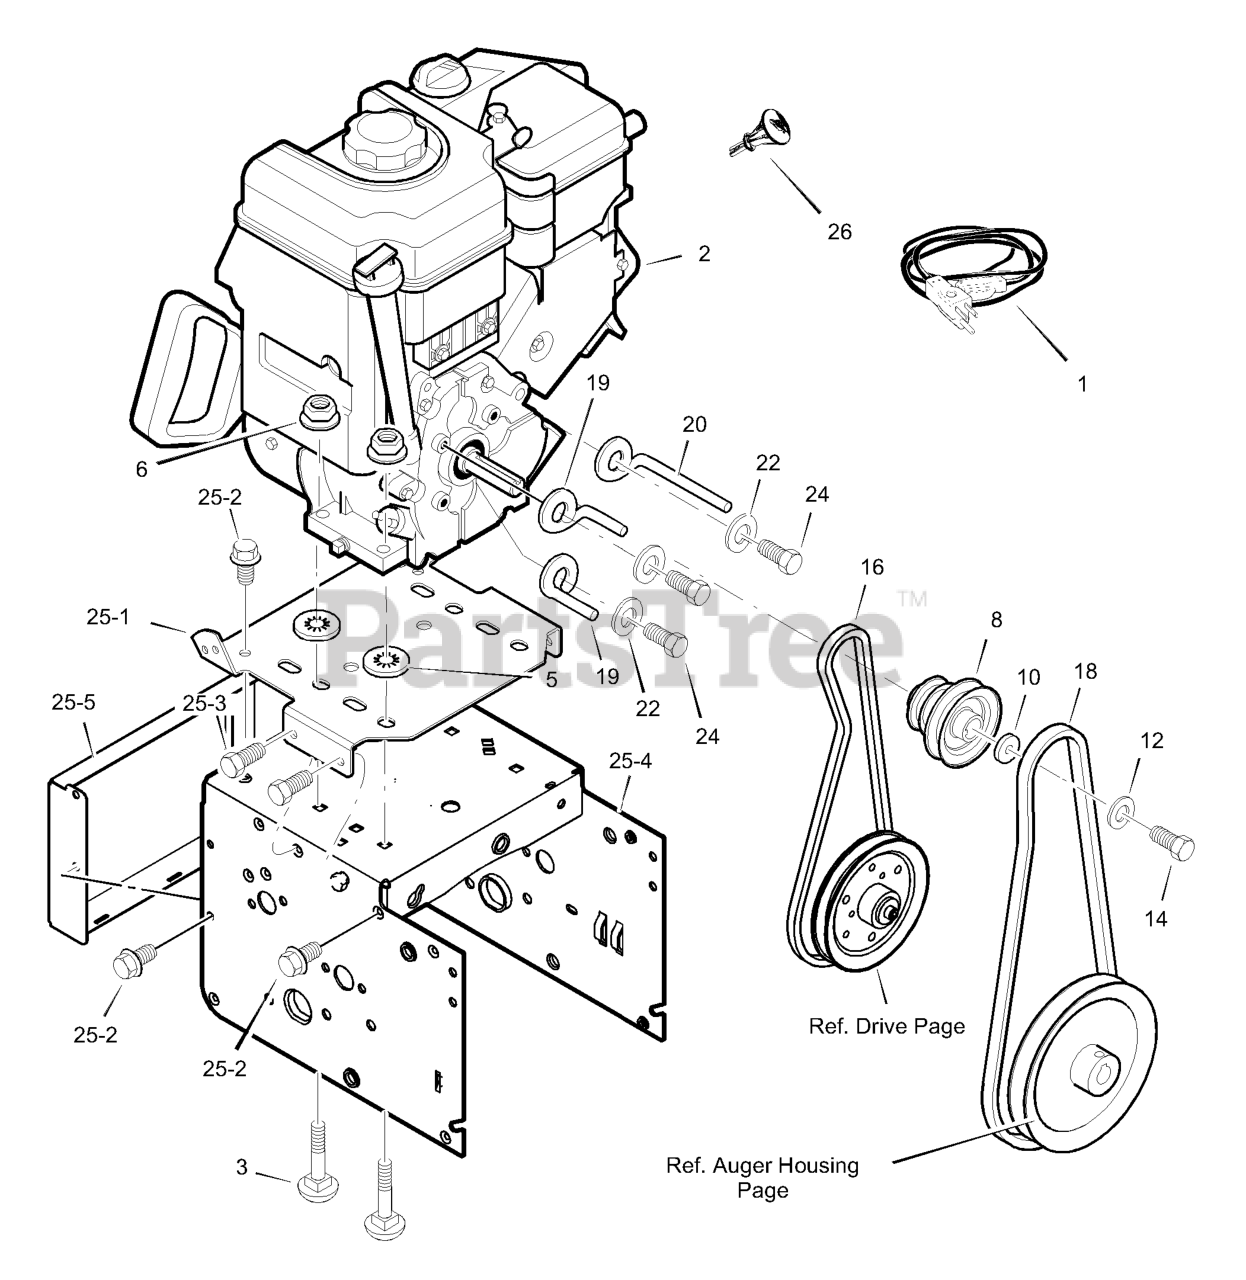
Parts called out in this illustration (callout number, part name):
1	CORD, STARTER
2	ENGINE
3	BOLT, CARRIAGE 5/16-18
5	RETAINER, PUSH
6	NUT, HEX 5/16-18
8	PULLEY, ENGINE
10	WASHER
12	WASHER .38ID
14	SCREW, 3/8-24 x 1.00
16	BELT, HYDRO DRIVE
18	BELT, AUGER V 4L
19	GUIDE, BELT
20	GUIDE, BELT
22	WASHER, SPTLK .31X.58X.08
24	SCREW, 5/16-24 x 0.75
25	FRAME ASSEMBLY
25-1	PLATE, ENGINE MOUNT
25-2	SCREW, TAP 1/4-20 X .63
25-3	SCREW, TAP 5/16-18 X .50
25-4	FRAME, MOTOR BOX
25-5	PANEL, BACK - HYDRO
26	KEY, ENGINE
